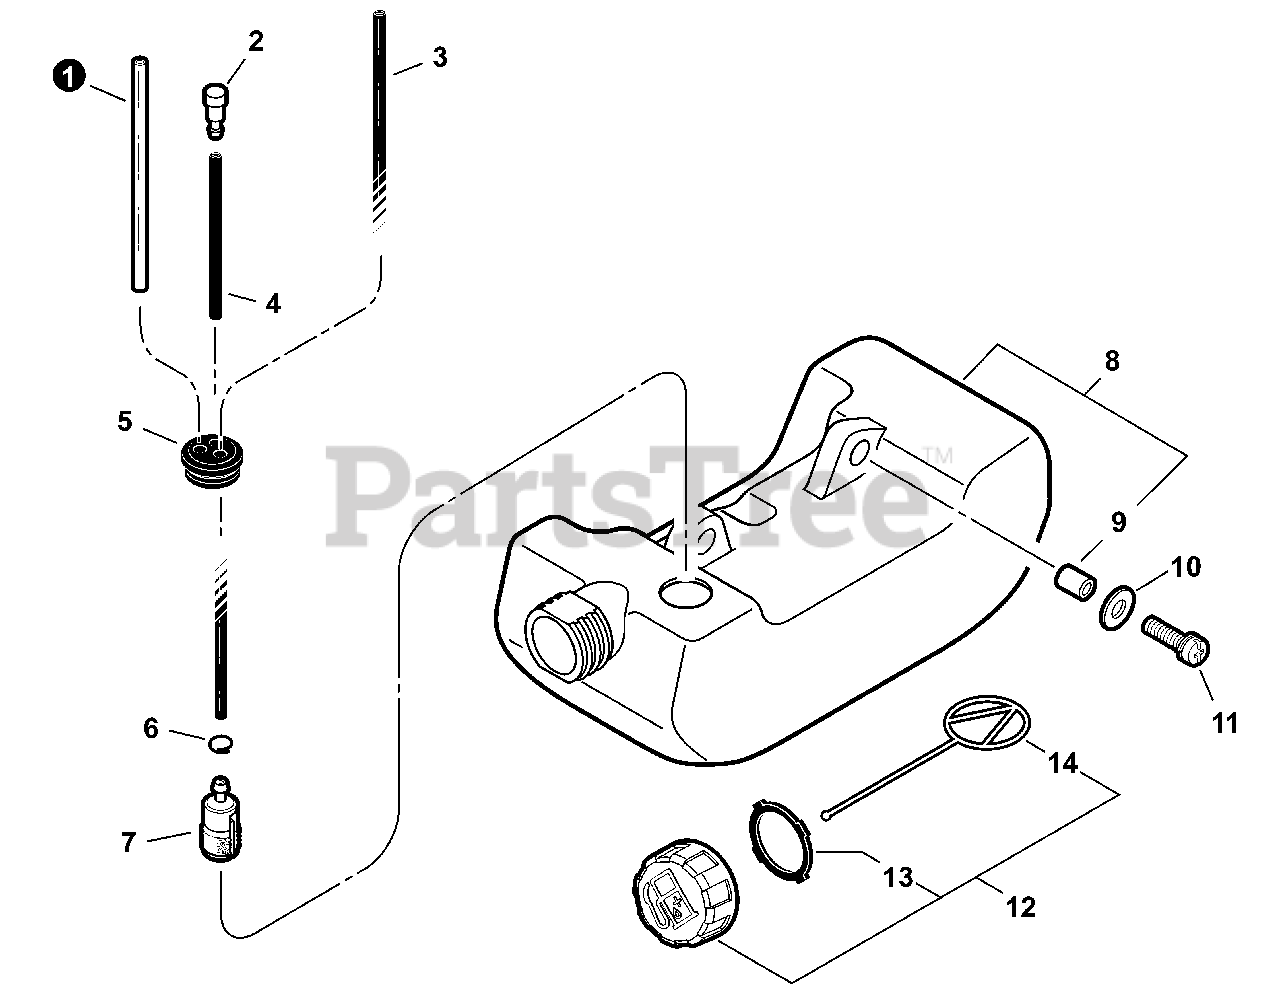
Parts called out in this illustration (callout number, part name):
1	PIPE, FUEL RETURN 3×6×90 MM CLEAR
2	VENT ASSY
3	PIPE, FUEL 3x-5x-180
4	PIPE, FUEL 3x-5x-70 BLACK
5	GROMMET, FUEL
6	CLIP 6 MM
7	FILTER, FUEL
8	TANK, FUEL
9	SPACER 6.2×7.8×6
10	WASHER 5.5×12×0.8
11	BOLT 5×16
12	CAP ASSY, FUEL
13	GASKET, FUEL CAP
14	CONNECTOR, CAP L= 100 MM
